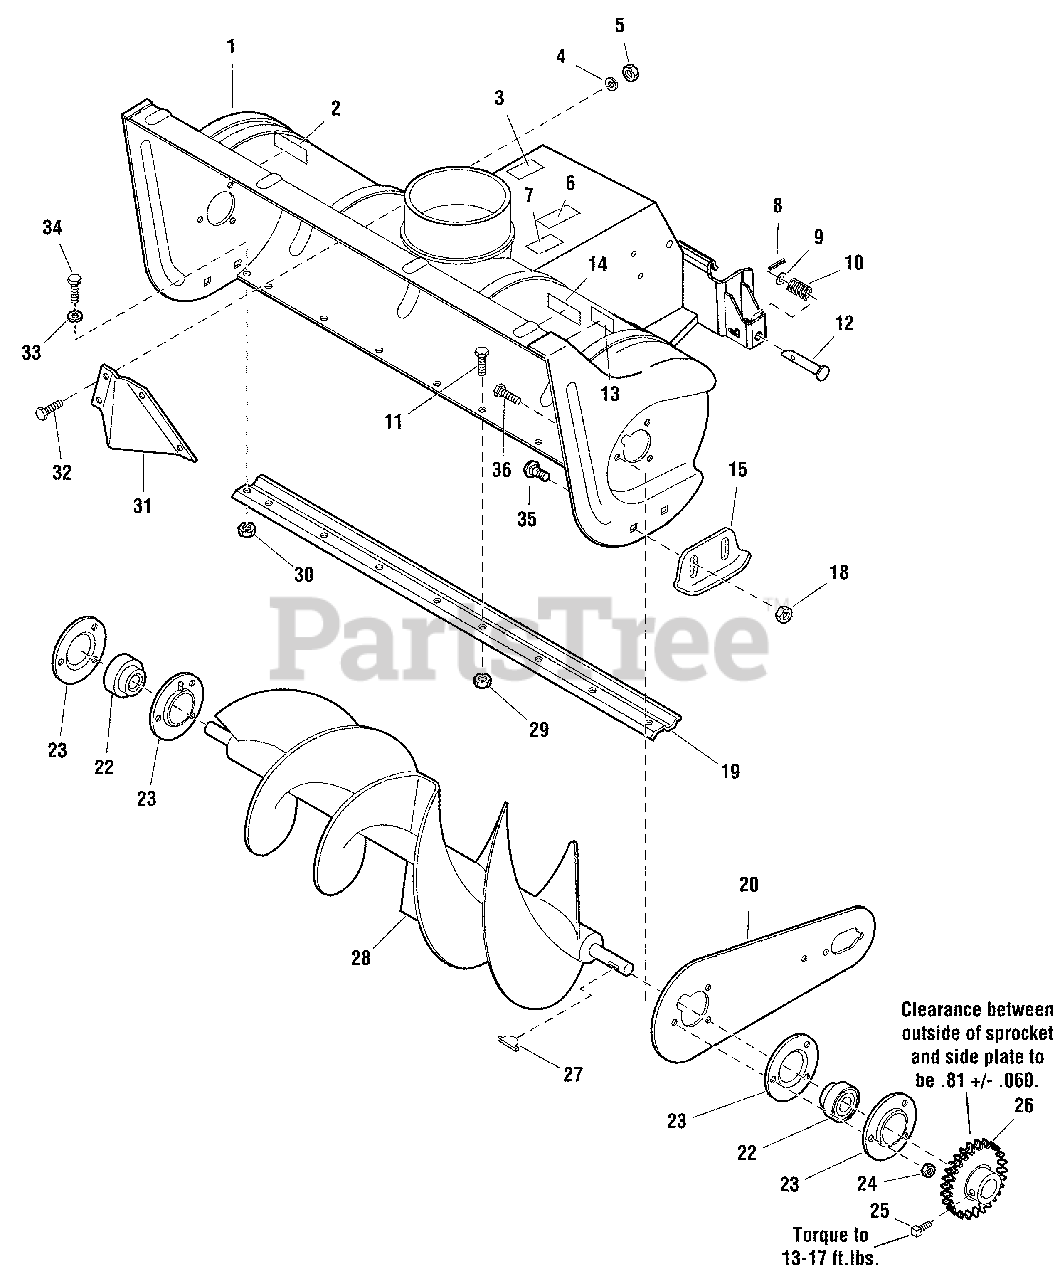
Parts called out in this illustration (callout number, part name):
1	BODY & FRAME ASSEMBLY
2	DECAL, Caution, Rear Wheel Weights Required
3	DECAL, Caution, Spring Tension
4	LOCKWASHER, 5/16
5	NUT, Hex, 5/16-18
6	DECAL, OPEI, Not Serviced
7	DECAL, Model Number & Serial Number, Not Serviced
8	PIN, Spring
9	WASHER, 5/8
10	SPRING, Compression
11	CAPSCREW, Hex Head, 1/4-20 x 5/8
12	PIN, Flat Head Drilled
13	DECAL, Danger Auger
14	DECAL, Caution
15	SKID & WEAR ASSEMBLY
18	NUT, ESNA Hex Flange, 3/8-16
19	BLADE, Scraper, 46"
20	PLATE, Side
22	BEARING, Cartridge
23	FLANGE, Bearing
24	NUT, Hex Flange Lock, 5/16-18
25	SCREW, Set, Hex Socket Head, Cup Point, 5/16-18 x 3/8
26	SPROCKET ASSEMBLY
28	ROTOR ASSEMBLY, 46"
29	NUT, Hex Centerlock, 1/4-20
30	NUT, Hex Centerlock, 5/16-18
32	CAPSCREW, Hex Head, 5/16-18 x 5/8
34	CAPSCREW, Hex Head, 5/16-18 x 3/4
35	CARRIAGE BOLT, Round Head Square Neck 3/8-16 x 3/4
36	CAPSCREW, Hex Head, 5/16-18 x 7/8
